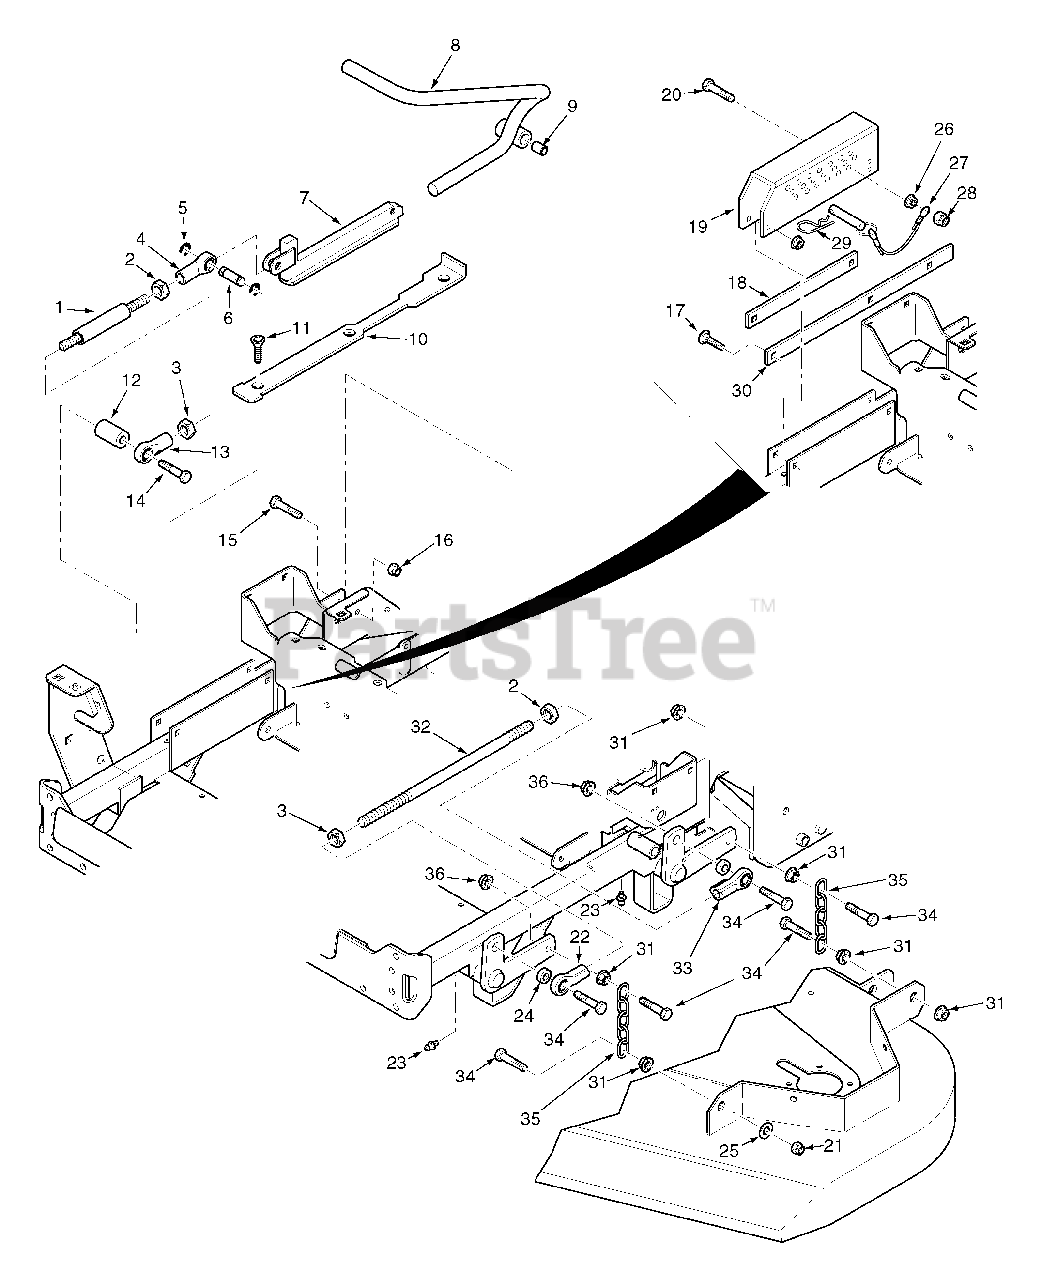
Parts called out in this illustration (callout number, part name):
1	Link, Deck Lift
2	Nut, 1/2-20 UNF LH Thread Jam
3	Nut, 1/2-20 UNF RH Jam
4	Rod End, 1/2-20 LH Female
5	Ring, Retaining 1/2" External "E"
6	Pin, Deck Lift
7	Slide, Deck Height Adjust
8	Deck Latch Weldment
9	Bushing, .502 O.D.
10	Lock Plate, Deck Lift
11	Screw, Cap 5/16-18 x 3" FHHS
12	Spacer, Foot Pedal SZC
13	Rod End, 1/2-20 RH Female
14	Bolt, Hex Head 1/2-13 x 3-1/2"
15	Bolt, Hex Head 3/8-16 x 2-1/2"
16	Nut, Elastic Stop 3/8-16
17	Bolt, Carriage 5/16-18 x 1"
18	Guide, Short
19	Bracket, Cutting Height Adjustment
20	Bolt, Hex Head 3/8-16 x 3-1/2"
21	Nut, Elastic Stop 3/8-16
22	Rod End, 1/2-20 RH Female
23	Grease Fitting, 1/4-28 Self Tap
24	Spacer
25	Flatwasher, 3/8-.391 x .938 x .105
26	Nut, Serr. Flange 3/8-16
28	Nut, Elastic Stop 3/8-16
29	Hair Pin Cotter, .177 x 3-1/4"
30	Guide, Long
31	Nut, Serr. Flange 3/8-16
32	Link, Lift 1/2-20 x 14.18"
33	Rod End, 1/2-20 LH Female
34	Bolt, Hex Head 3/8-16 x 1-1/2"
35	Chain
36	Nut, Center Lock 5/8-11
